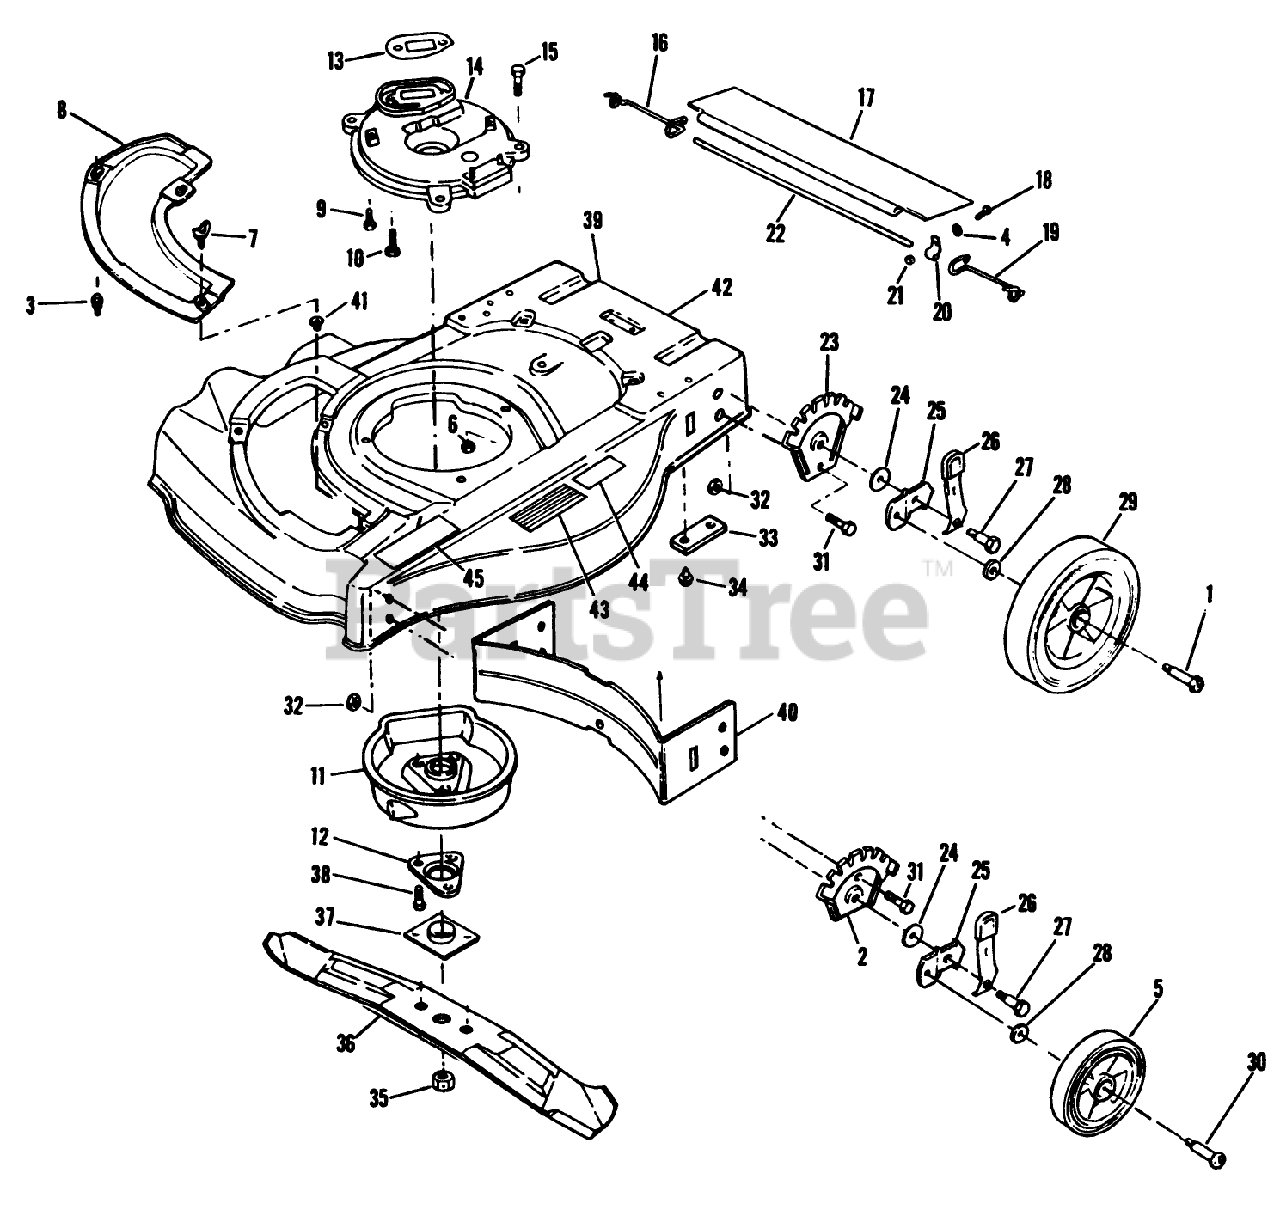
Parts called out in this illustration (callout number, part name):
2	PLATE HGT ADJ TRO
4	WASHER F
6	NUT-LOCK F
7	WING SCREW LAWRE
10	SCREW V
12	SUPPORT F
14	PLATE,MUFFLER F
15	SCREW
16	SPRING;TRAILING SHIELD RH
19	SPRIG T/SHLD ASOC
20	CLAMP ROD KMC
21	LOCKNUT E
22	ROD T/SHIELD ADV WIRE
24	WASHER
26	KNOB & SPRING
28	WASHER-PLAIN
32	LOCKNUT
34	SCREW
35	NUT-BLADE
37	PLATE AND COLLAR ASM
38	SCREW
42	Decal
43	PAD FOOT
44	Decal-Starting Pad
45	Decal
